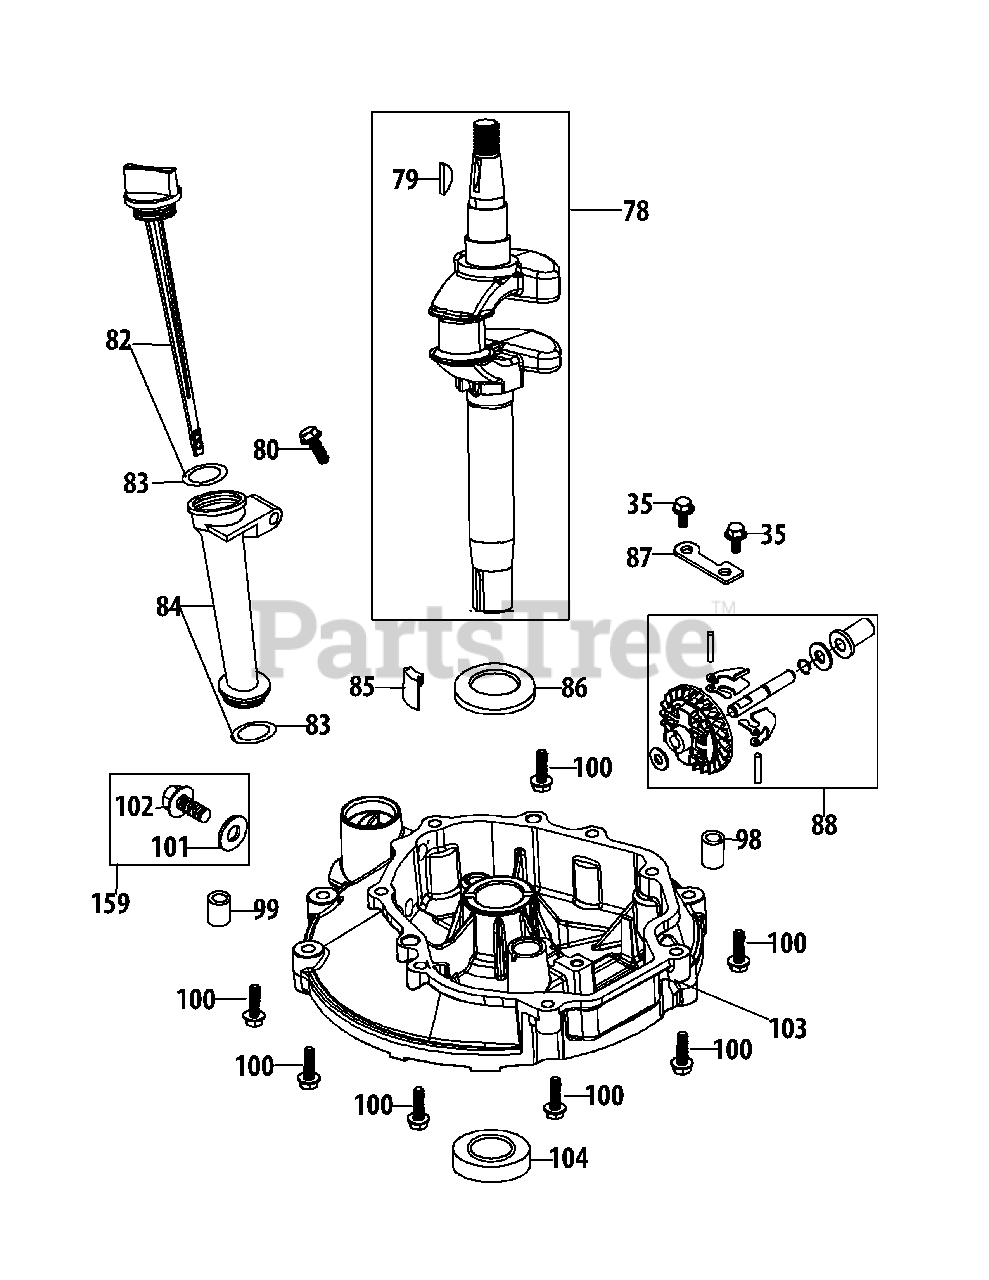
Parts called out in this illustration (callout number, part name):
35	Bolt M6X14 Multi-Purpose
78	Crankshaft Assembly
79	Flywheel Key
80	Bolt M6X35 Af Base/Brake/Dipstick
82	Oil Dipstick Assembly
83	Dipstick / Oil Fill Tube O-Ring
84	Oil Fill Tube Assembly
85	Oil Return Seal
86	Crankshaft Thrust Washer
87	Governor Gear Mounting Plate
88	Governor Gear/Shaft Assembly
98	Crankcase Cover Dowel Pin 7×14
99	Crankcase Cover Dowel Pin 9×14
100	Bolt M6X28 X65/P65 Crankcase
101	Oil Drain Plug Washer
102	Oil Drain Plug
103	Crankcase Cover
104	Lower Crankshaft Seal
159	Oil Drain Plug & Washer Ass'Y
